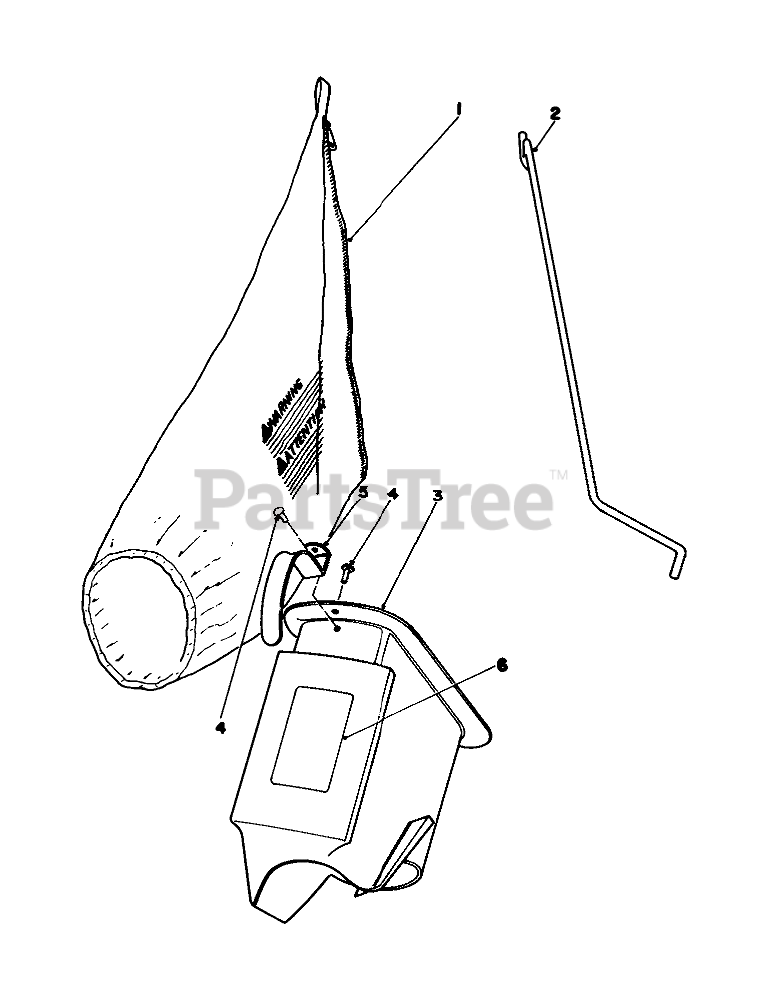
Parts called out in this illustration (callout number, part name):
1	BAG REPLACMNT44-0540
2	BAG ROD
3	Grass Chute (Incl. Ref. #4 & 5)
4	RIVET 3/16 X 7/16
5	HANDLE-GRASS CHUTE
6	BAG CHUTE DECAL
